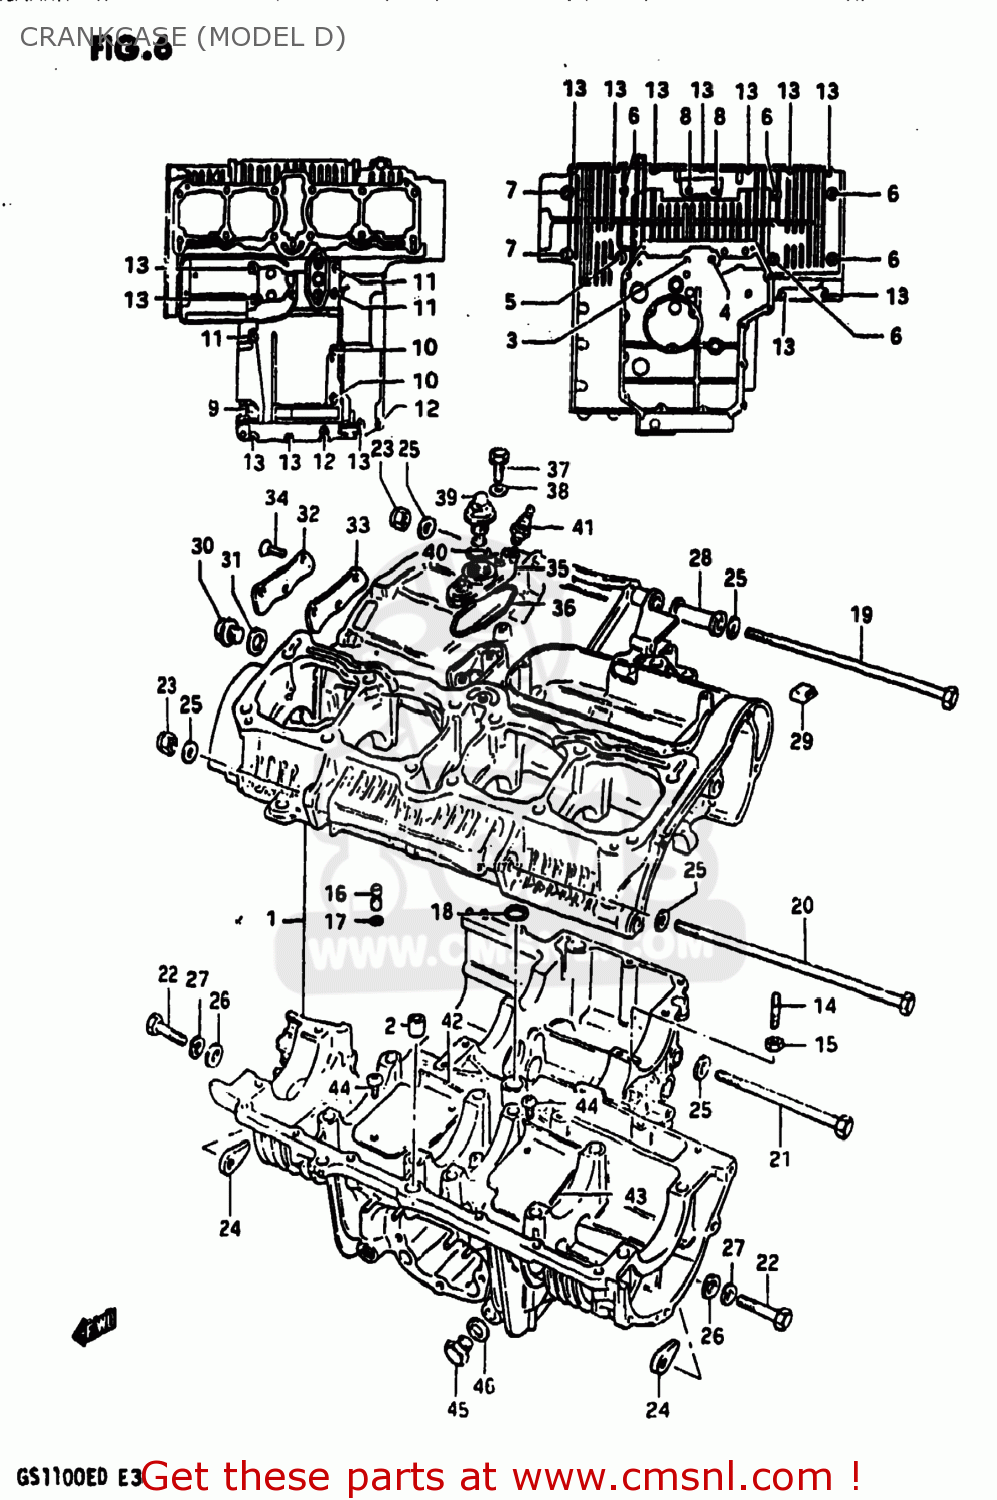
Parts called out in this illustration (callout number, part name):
1	CRANKCASE SET
2	PIN
3	BOLT 8X155
4	BOLT
5	BOLT
6	BOLT (8X90)
7	BOLT (8X65)
8	BOLT 8X60
9	BOLT (8X50)
10	BOLT
11	BOLT (6X75)
12	BOLT 6X55
13	BOLT (6X40)
14	STUD BOLT
15	NUT
16	UNION
17	O RING(D:1.05,ID:3.1)
18	O RING(D:3.2,ID:12.9)
19	BOLT 10X230
20	BOLT 10X250
21	BOLT(10X165)
22	BOLT (10X60)
23	NUT
24	NUT
25	WASHER
26	WASHER (10.5X20X3.2)
27	LOCK WASHER
28	SPACER,ENGINE MOUNT(L:65)
29	PAD,CYLINDER
30	PLUG (14X12)
31	GASKET(14X19.2X2) (NAS)
32	CAP,OIL GALLERY
33	GASKET,OIL GALLERY (MCA)
34	SCREW
35	HOUSING,OIL PRESSURE SWITCH
36	O RING,PRESSURE SWITCH HOUSING
37	BOLT
38	GASKET (NAS)
39	SWITCH ASSEMBLY
40	O RING(D:1.9,ID:18.8)
41	GAUGE ASSEMBLY,OIL TEMPERATURE
42	PLATE,OIL SEPARATOR
43	PLATE,OIL SEPARATOR
44	SCREW
45	PLUG
46	GASKET(14X19.2X2) (NAS)
